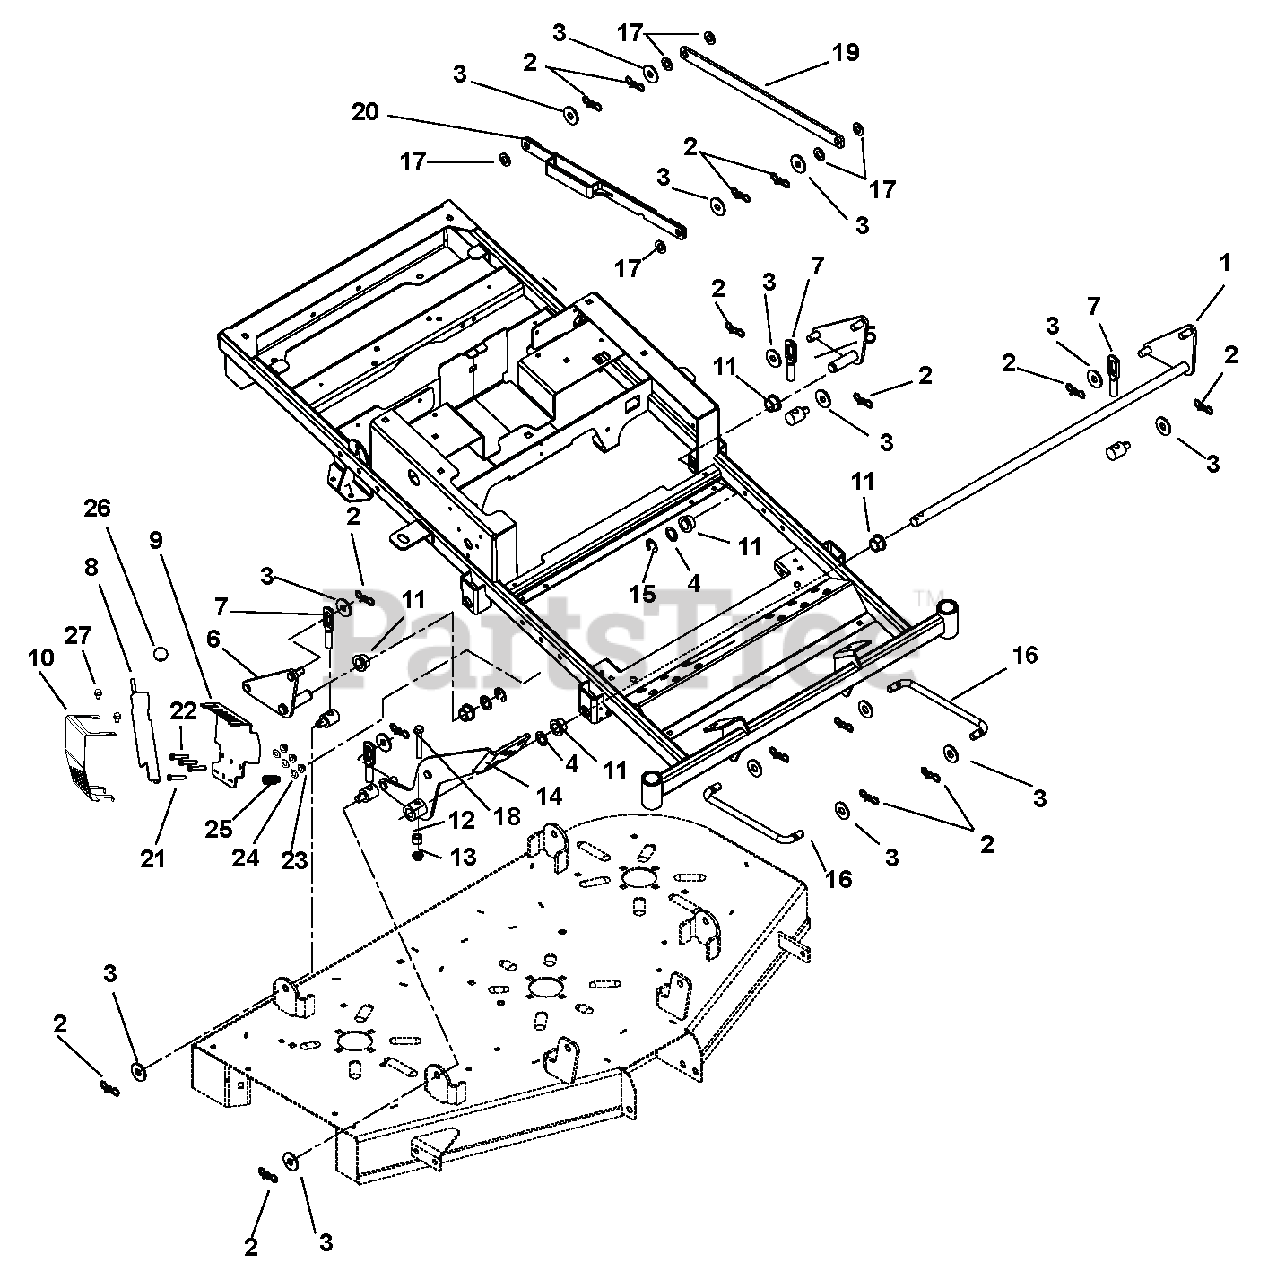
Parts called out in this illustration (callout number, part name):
1	WMT-DECK PIVOT FRONT
2	PIN,BOW TIE LOCKING .091X1.875
3	WSHR-FL-STL.511X1.441X.125 YWZ
4	WSHR-FL-STL.754X1.125X.062YWZC
5	WMT-DECK PIVOT ZTXL REAR LH
6	WMT-DECK PIVOT ZTXL REAR RH
7	ASM, DECK LINK
8	LEVER, HOC WLDMT XL
9	BRACKET, HOC XL
10	GUARD, PLATE STYLED HOC XL
11	BSHG-FLG .750X1.000X.625X1.250
12	BSHG-SLV .391X.688X.52 PM
13	@NUT-LK-NYL-FLG .38-16 YWZC
14	WMT-ZTXL FOOT PEDAL
15	RG-RTNG-EXT .750X.050
16	LINK, DRAG
17	WSHR-FL-NYL .518X1.000X.080
18	@BLT-HEX .38-16X2.50 GR5 YWZC
19	LINK, LIFT
20	HOC, LINK RETAINING XL
21	@BLT-HEX .38-16X2.25 GR5 YWZC
22	@BLT-HEX .38-16X1.75 GR5 YWZC
23	@NUT-LK-NYL-FLG .38-16 YWZC
24	@WSHR-FL-STL.38X.875X.083 YWZC
25	SPRING, COMPRESSION
26	KNOB,BALL -BLACK 1.47" .375-16
27	SCR-TAP .25-20X.50 HWH TR YWZ
